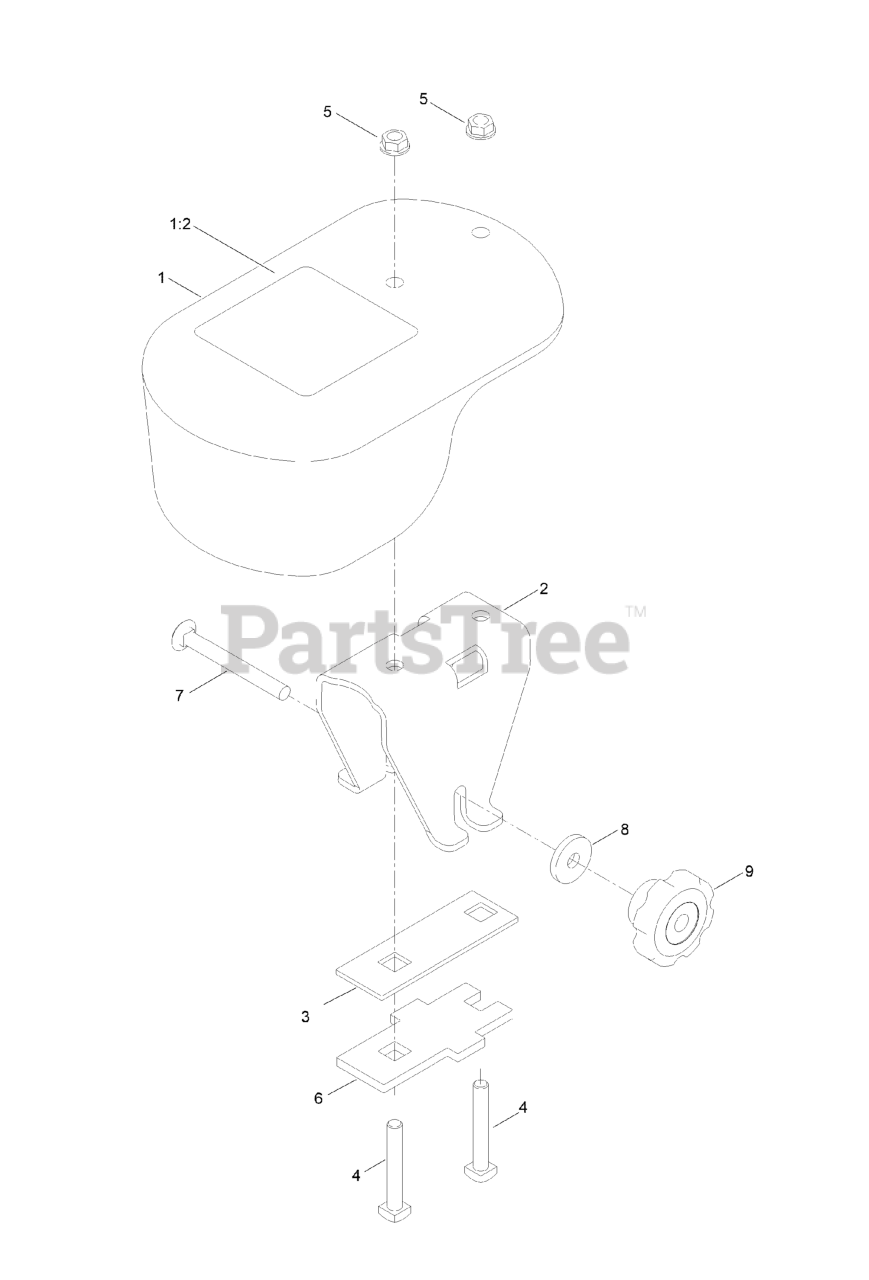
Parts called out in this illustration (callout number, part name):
1	WEIGHT WITH DECAL ASM
1:2	DECAL-WARNING, TRACTION
2	CHANNEL-MOUNT, WEIGHT
3	PLATE-BRACKET, WEIGHT
4	BOLT-SQH
5	NUT-HHF, WHIZ
6	PLATE-BRACKET, WEIGHT
7	SCREW-CARR
8	WASHER-BACKUP
